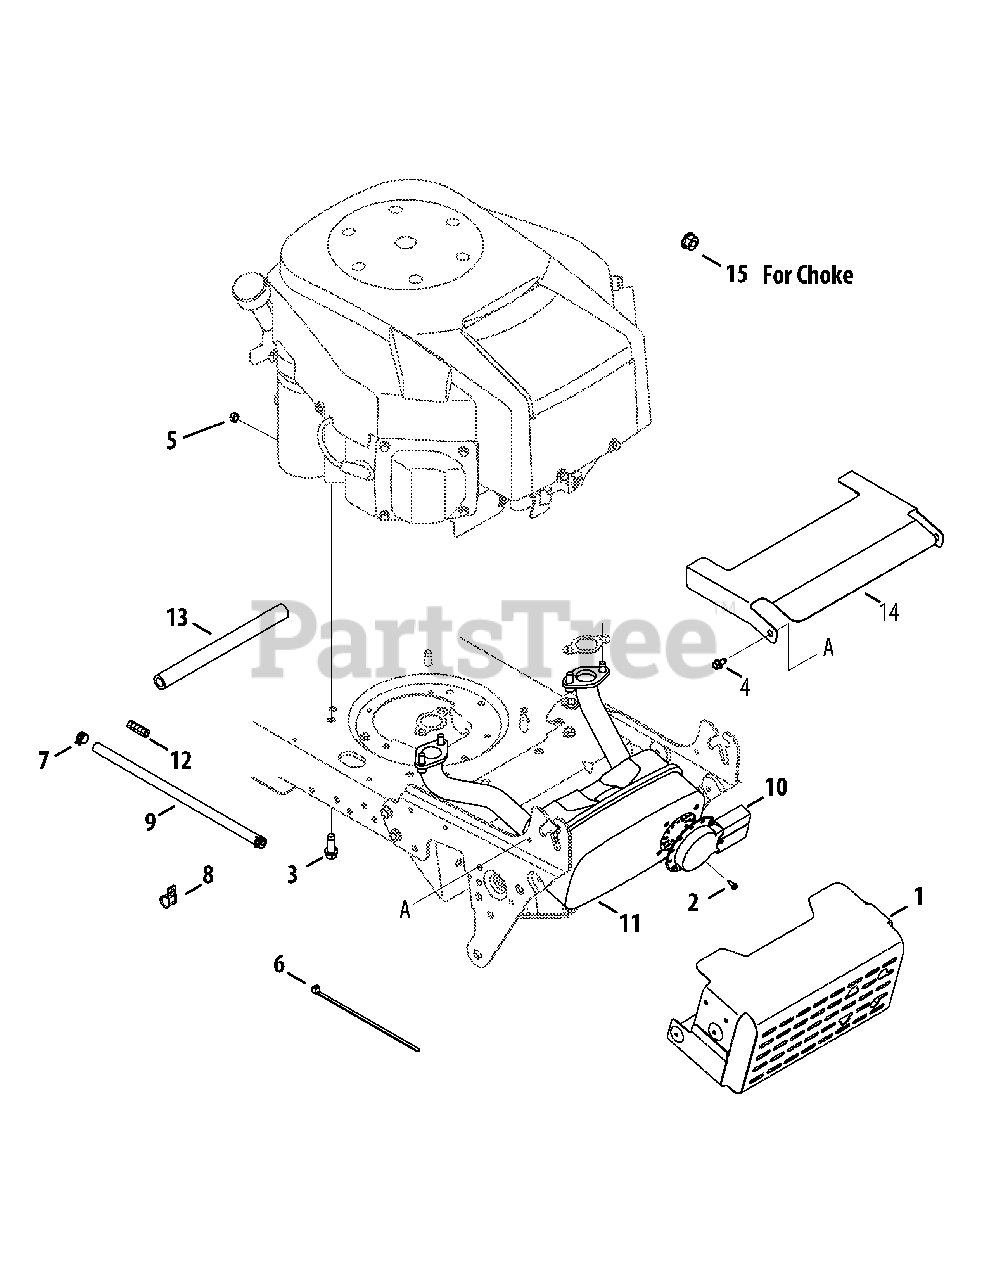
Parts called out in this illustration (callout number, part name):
1	Shield Ass’y, Muffler
2	Screw, Ab, #8-18, 0.500,
3	Screw, Self-tapping, 3/8-16, 1.250,
4	Screw, Self-tapping, 1/4-20, 0.500,
5	Nut, Sems, 1/4-20
6	Cable, Tie, 3/16 x .05 x 7.4
7	Clamp, Hose, .490 Dia.
8	Clamp, 1.0 Dia.
9	Hose, Fuel, Low Permeation, 1/4
10	Deflector, Muffler, Long
11	Muffler, Twin, Kawasaki
11	Muffler, Twin, kawasaki (CA)
13	Hose, Extension, Oil Drain
14	Heat Shield
15	Nut, 3/8-16, Flangelock
